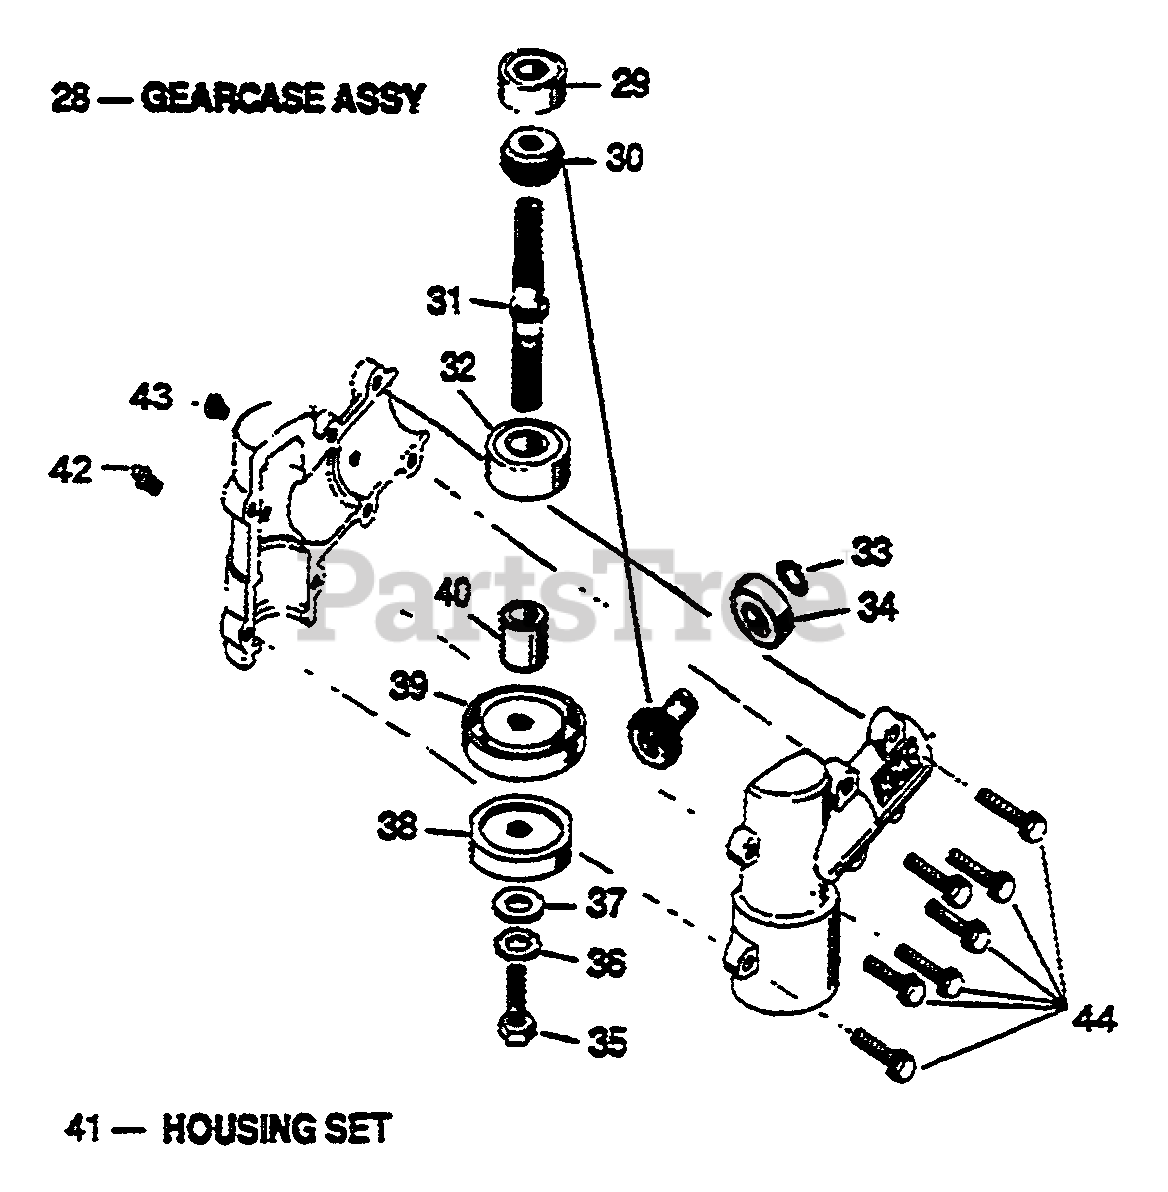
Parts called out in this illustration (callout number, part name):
28	GEARCASE ASSY
29	BEARING
30	GEAR SET KIT
31	SHAFT, GEAR
33	RING
34	BEARING
35	BOLT
36	WASHER
38	HOLDER B
41	HOUSING SET
42	FITTING ZERK
43	SCREW-SELF TAPPING
44	SCREW-SELF TAPPING
